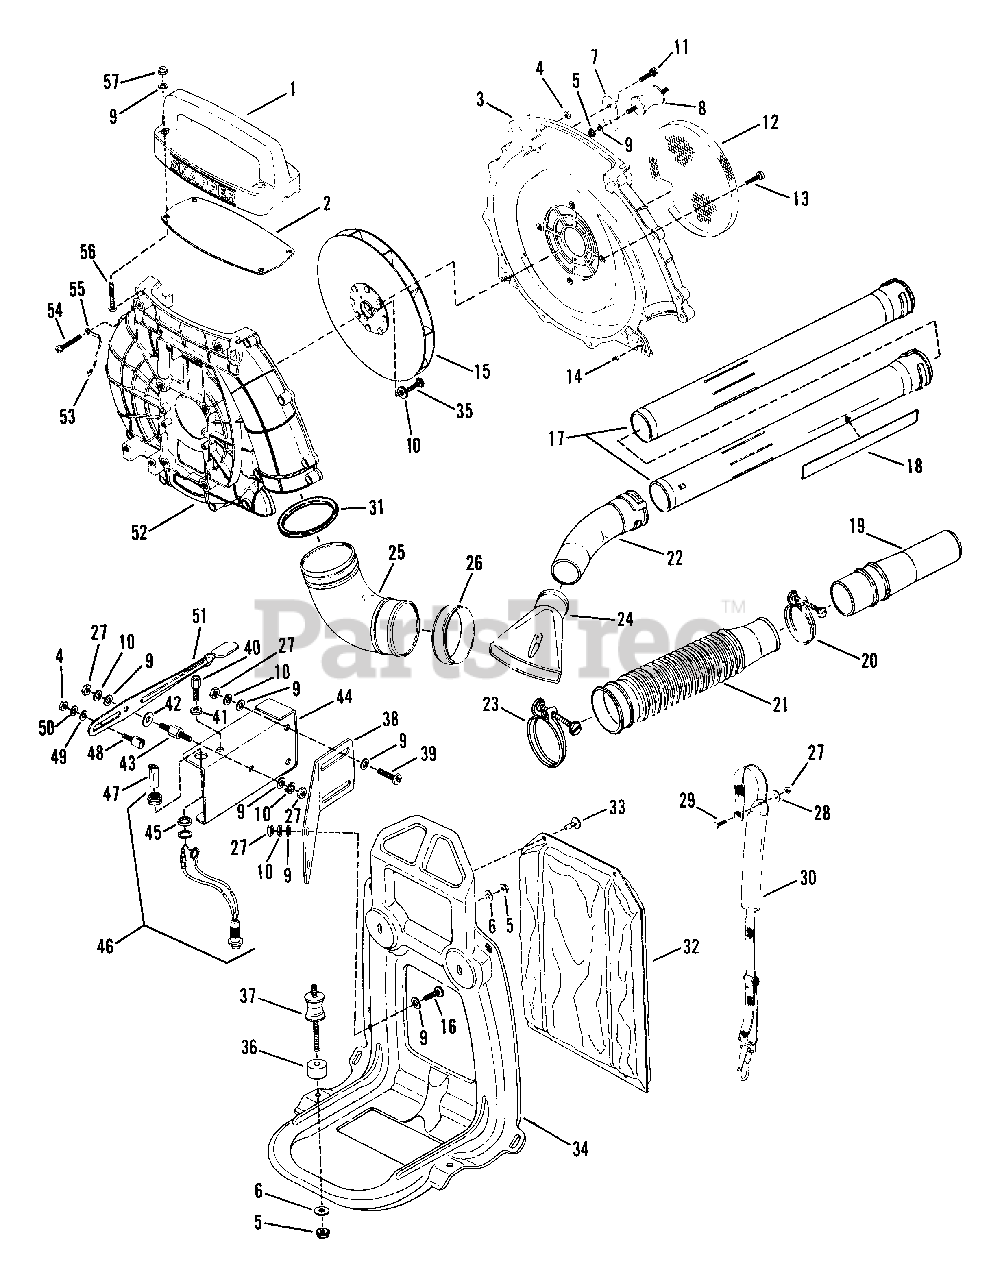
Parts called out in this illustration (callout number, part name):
2	GASKET, Handle
3	FANCASE, "A"
4	NUT, M5
5	NUT, M6(Flange Lock)
6	WASHER, Flat, M6 (Special 6.5 I.D.x 18mm O.D.)
7	BRACKET, Isolator Mount
8	VIBRATION ISOLATOR MOUNT
9	WASHER, M6 (Std. Flat)
10	LOCKWASHER, M6
11	BOLT, M6 x 25mm, with F.W. & L.W.
12	SCREEN, Mesh
13	SCREW, M6 x 15mm, P.P.H. Sems F.W.
14	NUT, M6 (Special)
16	SCREW, M6 x 16mm Phillips
17	PIPE, Straight
18	DECAL, Snapper
19	PIPE, Swivel
20	CLAMP, Wire, #78
21	PIPE, Flexible
22	PIPE, Curved
23	CLAMP, Wire, #92
24	BLOW HEAD, Fan Shaped
25	PIPE, Curved
26	SLEEVE, Rubber
27	NUT, M6 (Std.)
28	WASHER, Coned (Special)
29	BOLT, M6, Slotted (Special)
30	SHOULDER STRAP
32	PAD, Cushion
33	FASTENER (Plastic)
35	HEX BOLT, M6 x 16mm
36	SPACER (2)
37	VIBRATION ISOLATOR MOUNT
38	BRACKET
39	SCREW, M6 x 12mm P.P.H.
40	RECEIVER, Cable
41	NUT, M6 (Special)
42	WASHER, M6 (Special)
43	STUD, M6
44	PLATE, Throttle Support
45	WASHER (8mm I.D.x 15mm O.D. Special)
46	SWITCH, Stop
48	RECEIVER-STUD, Wire
49	WASHER, M5
50	LOCKWASHER, M5
51	LEVER, Throttle
52	FANCASE, "B"
53	SLEEVE, Plastic
54	SCREW, M5 x 35mm FW, P.P.H.
55	CLIP, Cable
56	HEX BOLT, M6
57	NUT, M6 (Acorn style)
